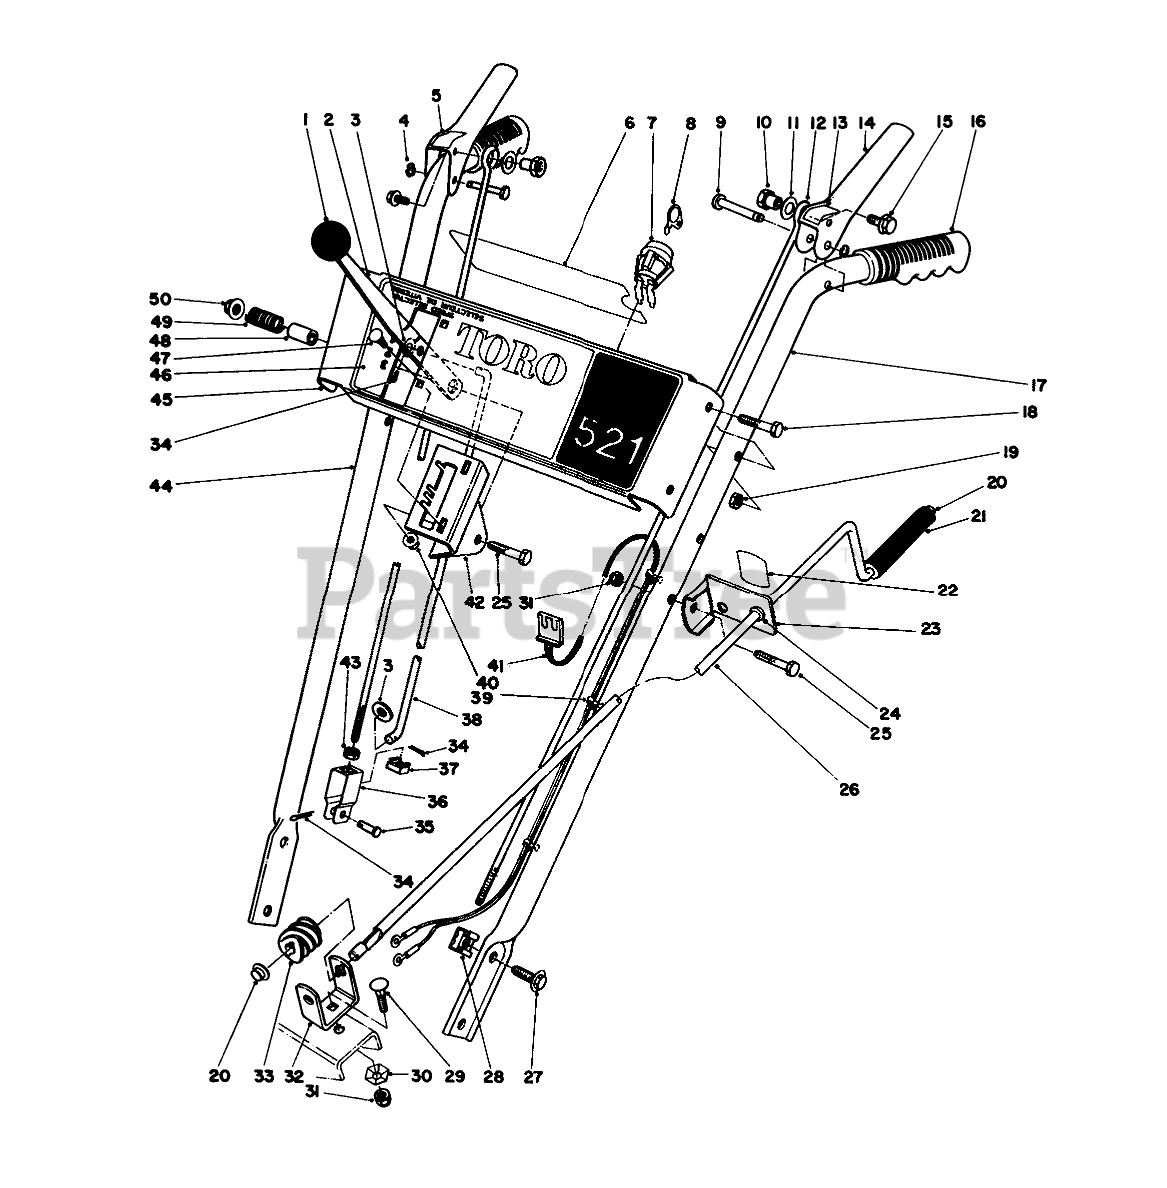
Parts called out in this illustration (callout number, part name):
2	SPEED SELECTOR B
3	WASHER-PLAIN
4	RING-CLIP
5	AUGER DRIVE DECAL
6	Decal-Escutcheon Back
7	SWITCH
8	Key
9	PIN-LEVER, CONTROL
10	POST-MOUNTING, LINKAGE
11	WASHER-FLAT
12	LINK-UPPER
13	DECAL
14	Handle-Control
15	SCREW-HHF
16	Grip
17	LEFT HANDLE
18	SCREW-HH
19	NUT-LOCK, CONE
20	RETAINER-PUSH ON
21	GRIP-CONTROL, CHUTE
22	CHUTE DECAL
23	Bracket-Chute Control (Incl. Ref. #22 & 24)
24	Bushing
25	SCREW-HH
26	ROD-CONTROL, CHUTE
27	SCREW-HHF
29	BOLT-CARR
30	WASHER-LOCK
31	NUT-LOCK, NI
32	BRACKET-WORM
33	GEAR-WORM, CHUTE
34	PIN-COTTER
35	PIN-CLEVIS
36	CLEVIS
37	NUT-RETAINED
38	ROD-SELECTOR, SPEED
39	Mount-Wire
40	NUT-HHF
41	Wire Harness Assembly (Incl. Ref. #39)
42	Mount-Speed Selector
43	NUT-JAM
44	RIGHT HANDLE
45	ESCUTCHEON PLT B
46	CONT PLT DECAL 521
47	SCREW-CARRIAGE
48	SPACER
49	SPRING
50	NUT-HF
